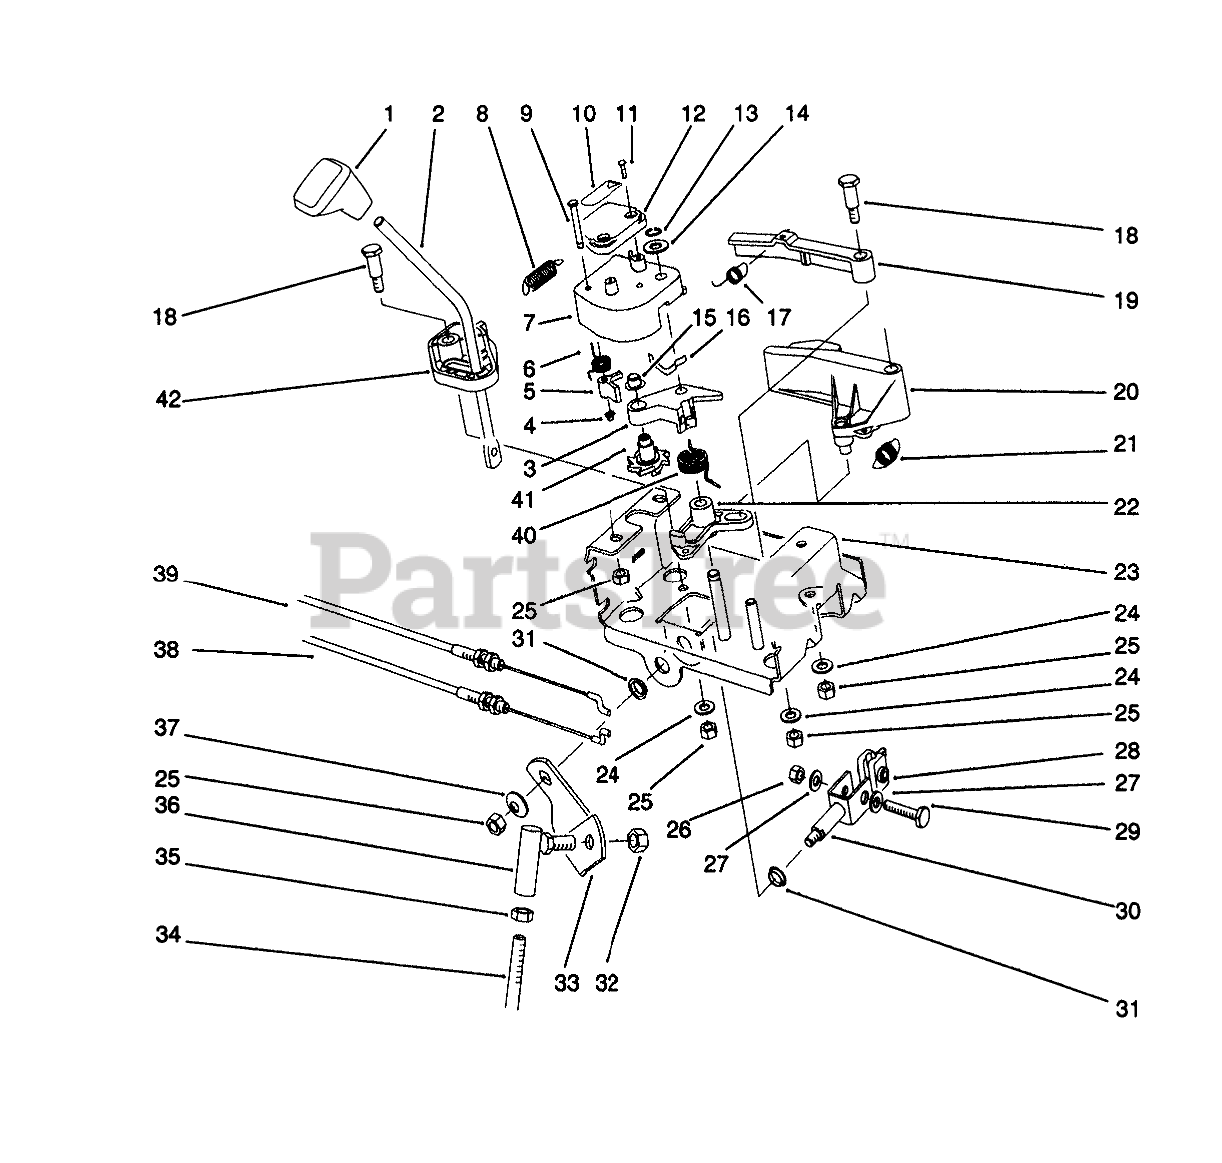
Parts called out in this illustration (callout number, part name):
1	KNOB-SHIFT
2	ROD-SHIFT
3	LEVER-WHEEL, INDEX
4	NUT-PUSH
5	TANG-INDEX
6	SPRING-TORSION
7	LATCH-LEVER
8	SPRING-EXTENSION
9	PIN-TANG
10	DECAL
11	SCREW-PPH
12	COVER-LATCH
13	RING-RETAINING
14	WASHER-THRUST
15	RETAINER-PUSH ON
16	SPRING-FLAT
17	SPRING-EXTENSION
18	SCREW-SHOULDER
19	LEVER-LOCKOUT
20	LEVER-REVERSE
21	SPRING-EXTENSION
22	LEVER-REVERSE, SWITCH
23	Frame-Control
24	WASHER-PLAIN
25	NUT-LOCK, NI
26	NUT-LOCK, NI
27	WASHER-FLAT
28	RETAINER-ROD, SHIFT
29	SCREW-HH
30	CLEVIS ASM
31	BUSHING
32	NUT-LOCK, NI
33	BRACKET-SHIFT
34	ROD-BENT SHIFT, LOWER
35	NUT-HJ
36	JOINT-BALL
37	WASHER-BELLEVILLE
38	CABLE-GEARBOX
39	CABLE-ARM, LATCH
40	SPRING-TORSION
41	WHEEL-INDEX
42	BASE-LOCKOUT
